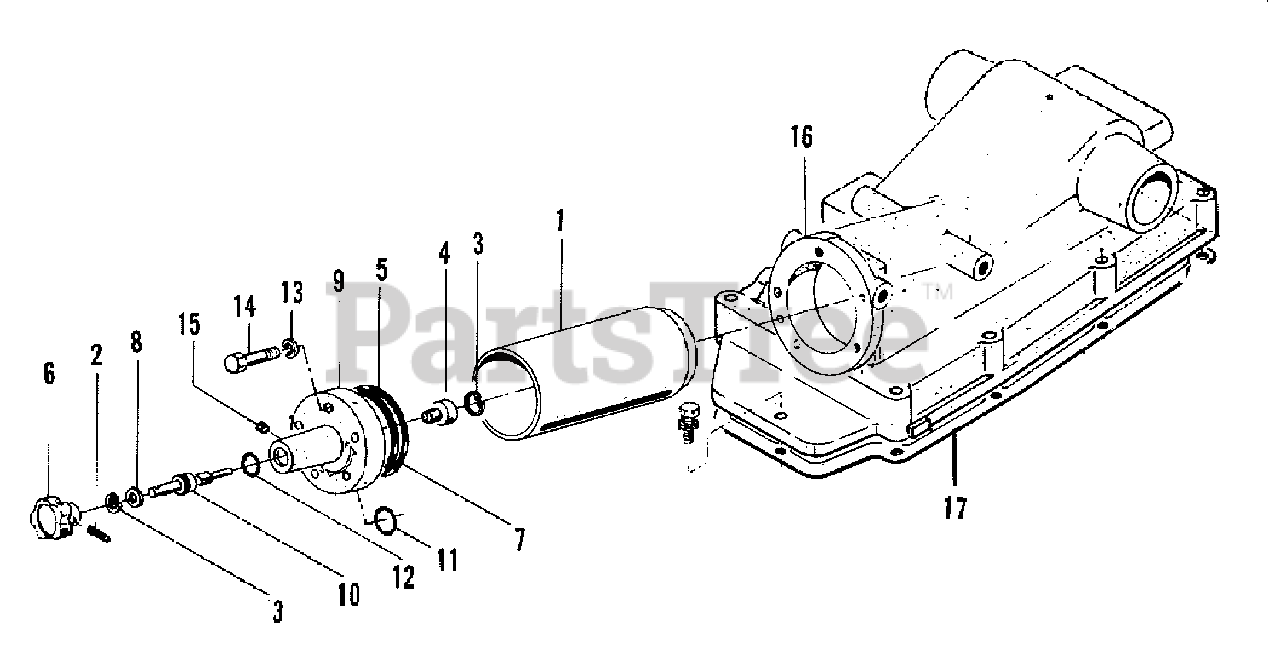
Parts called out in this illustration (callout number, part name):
1	LINER, housing
2	PIN, M4 x 20, roll
3	RING, snap
6	GRIP, adjust
9	COVER, housing
10	SCREW, lower adjust
13	LOCKWASHER, M10
16	HOUSING, lift
17	GASKET, housing
